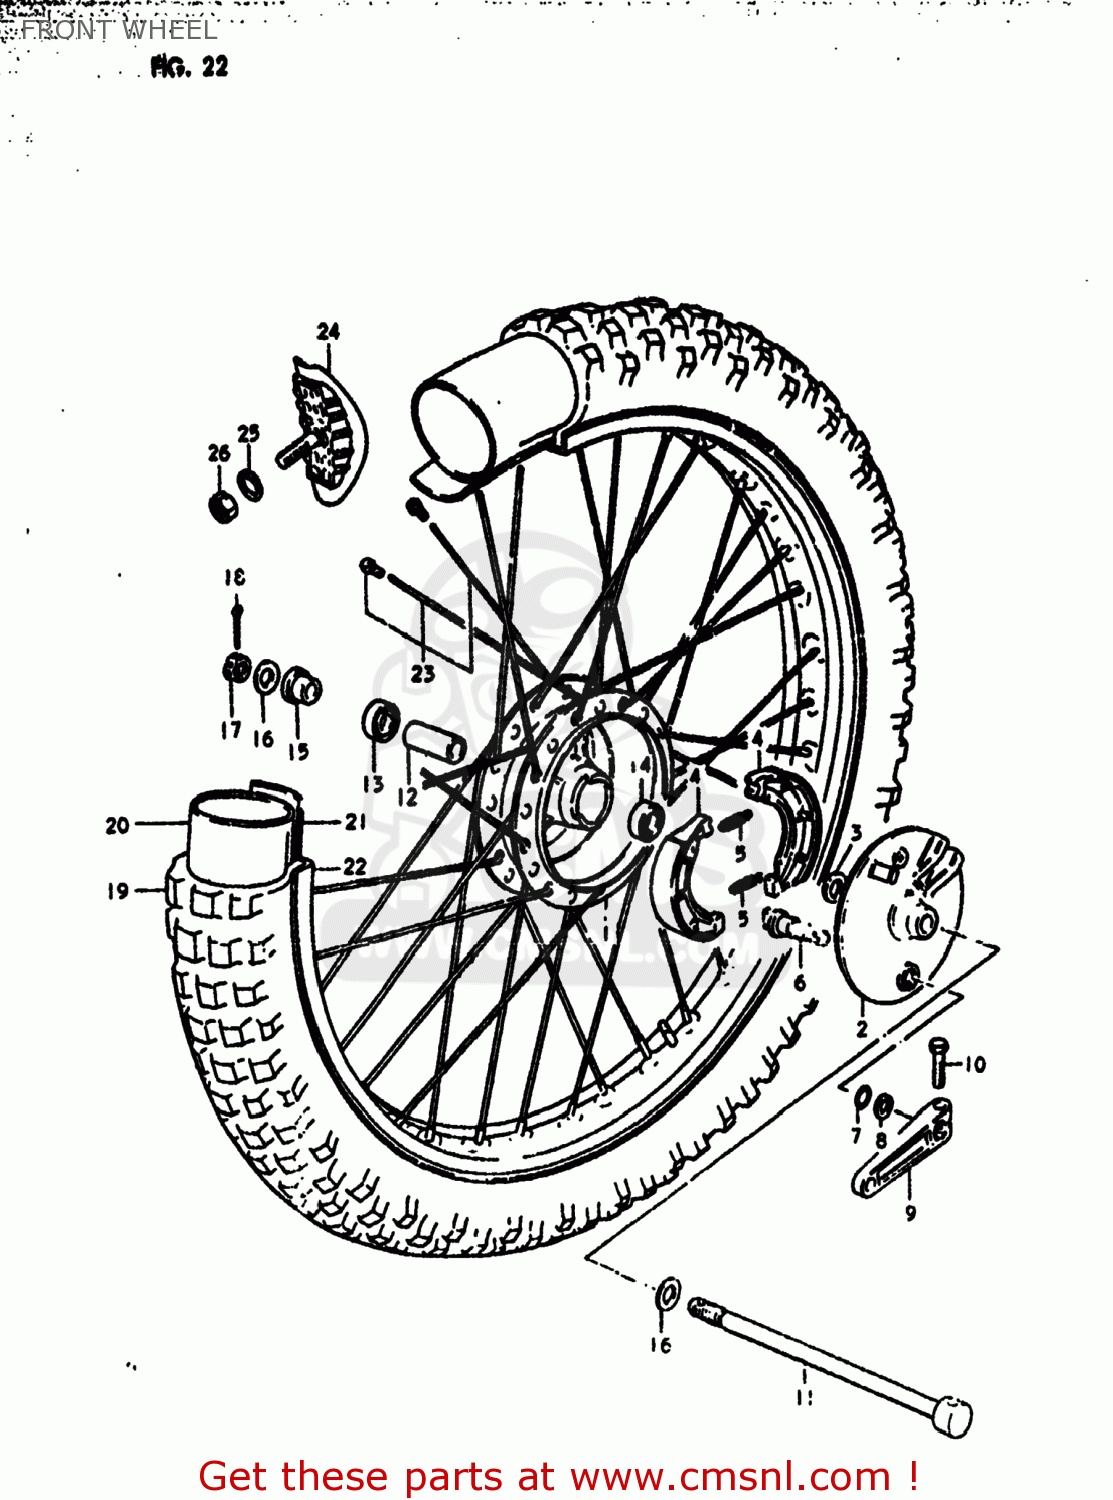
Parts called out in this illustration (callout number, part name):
1	HUB,FRONT
2	PANEL,FRONT HUB
3	BOSS
4	SHOE,BRAKE
5	SPRING(L:34)
6	CAM,FRONT BRAKE
7	O RING(D:2.5,ID:11.4)
8	WASHER(12.5X20X1)
9	LEVER,FRONT BRAKE CAM
10	BOLT
11	AXLE,FRONT
12	SPACER (12.6X19X52)
13	BEARING, RH
14	BEARING
15	SPACER,FRONT AXLE,RIGHT
16	WASHER
17	NUT, REAR AXLE
18	COTTER PIN
19	TIRE,FRONT
20	TUBE,INNER
21	PROTECTOR,WHEEL,INNER
22	RIM,FRONT WHEEL
23	SPOKE SET,FRONT
24	STOPPER,BEAD
25	WASHER
26	NUT
